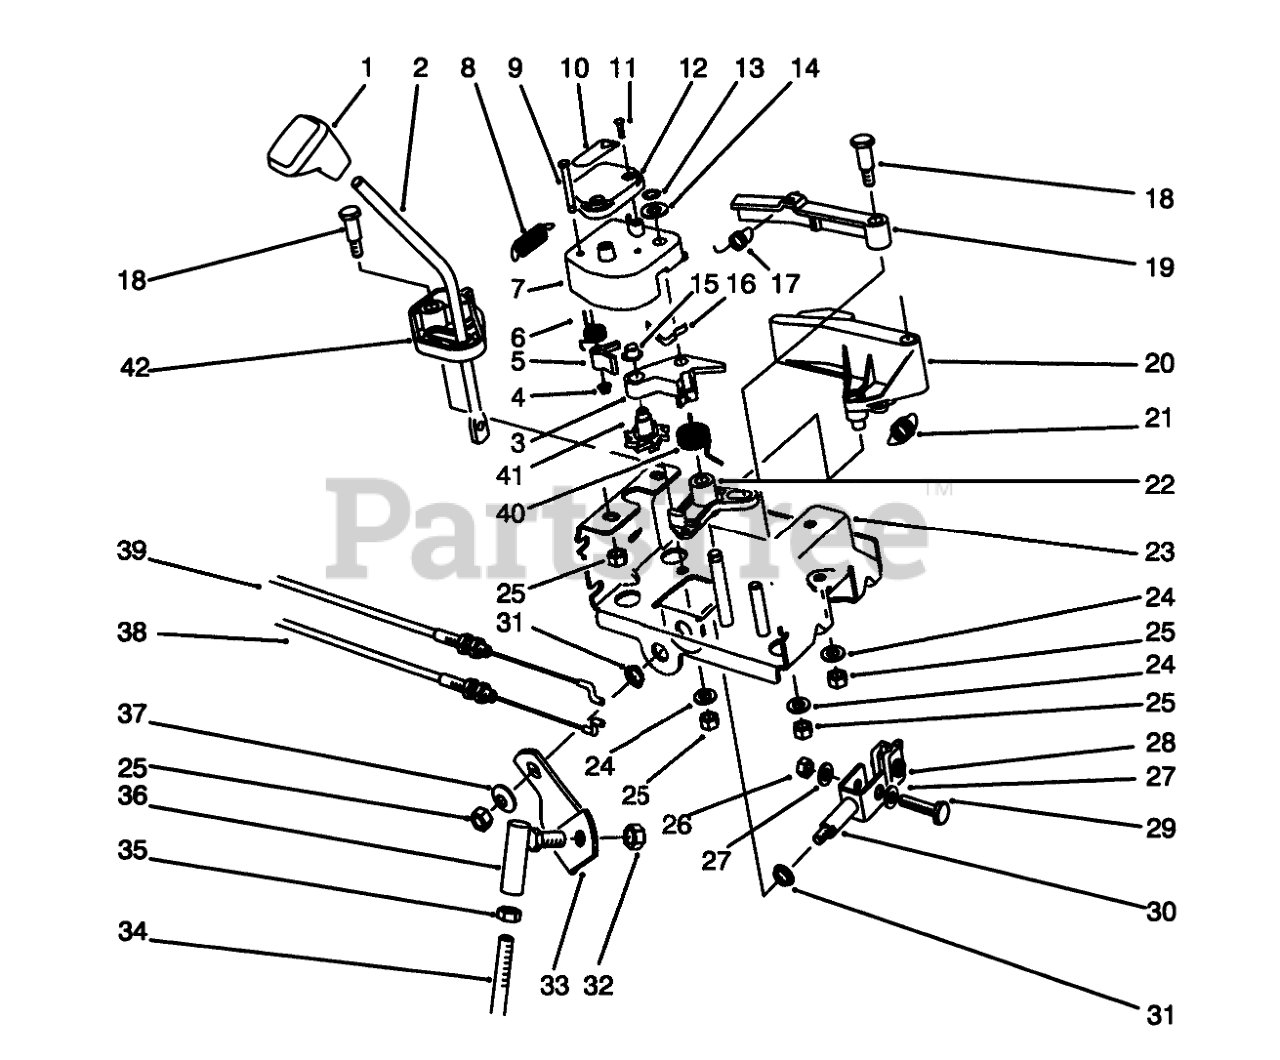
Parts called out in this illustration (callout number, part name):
1	KNOB-SHIFT
2	ROD-SHIFT
3	LEVER-WHEEL, INDEX
4	NUT-PUSH
5	TANG-INDEX
6	SPRING-TORSION
7	LATCH-LEVER
8	SPRING-EXTENSION
9	PIN-TANG
10	DECAL
11	SCREW-PPH
12	COVER-LATCH
13	RING-RETAINING
14	WASHER-THRUST
15	RETAINER-PUSH ON
16	SPRING-FLAT
17	SPRING-EXTENSION
18	SCREW-SHOULDER
19	LEVER-LOCKOUT
20	LEVER-REVERSE
21	SPRING-EXTENSION
22	LEVER-REVERSE, SWITCH
23	Frame-Control
24	WASHER-PLAIN
25	NUT-LOCK, NI
26	NUT-LOCK, NI
27	WASHER-FLAT
28	RETAINER-ROD, SHIFT
29	SCREW-HH
30	CLEVIS ASM
31	BUSHING
32	NUT-LOCK, NI
33	BRACKET-SHIFT
34	ROD-BENT SHIFT, LOWER
35	NUT-HJ
36	JOINT-BALL
37	WASHER-BELLEVILLE
38	CABLE-GEARBOX
39	CABLE-ARM, LATCH
40	SPRING-TORSION
41	WHEEL-INDEX
42	BASE-LOCKOUT
